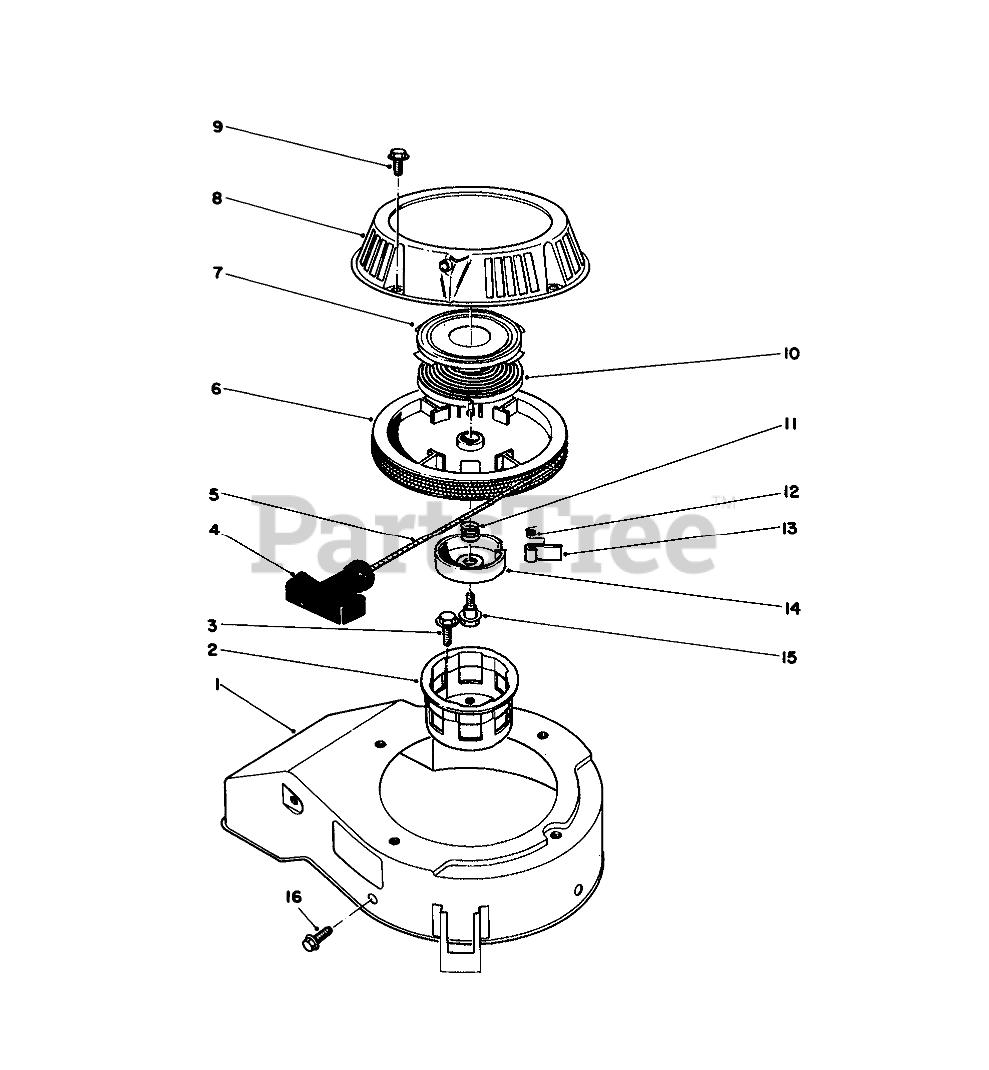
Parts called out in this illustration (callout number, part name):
1	COVER
2	CUP - STARTER
4	HANDLE-RECOIL
5	ROPE-STARTER
7	Retainer-Recoil Spring
9	SCREW-HHF
10	Spring-Recoil
11	SPRING
12	SPRING
14	RETAINER
